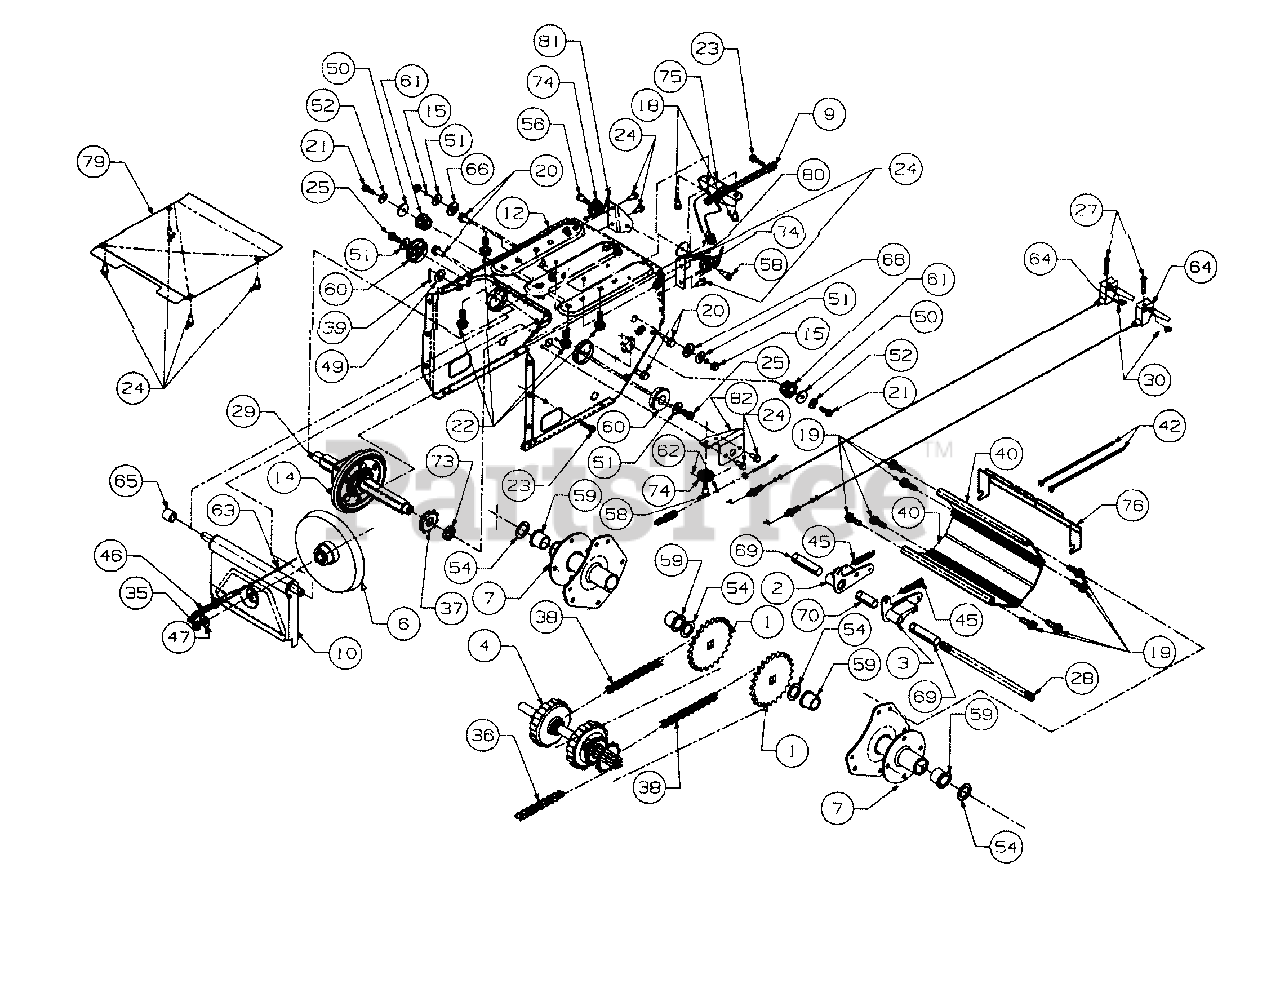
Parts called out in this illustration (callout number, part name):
1	Axle Assembly
2	Dog Assembly - R.H.
3	Dog Assembly - L.M.
4	Shaft Assembly
6	Disc Assembly
14	Wheel Assembly Friction
15	Screw
18	Screw
19	Screw
20	Screw
21	Screw
23	Screw
24	Screw
25	Screw
27	Screw
28	Shaft
29	Shaft
30	Nut Flange
35	Nut Jam
36	Chain
37	Sprocket
38	Chain
39	Pin Cotter
40	Housing Track
42	Cable Tie
45	Spring
46	Spring
47	Washer-Bell
49	Washer-Flat
50	Washer-Flat
51	Washer-Bell
52	Washer-Bell
54	Washer-Flat
56	Lubricant
58	Screw-Shoulder
59	Bearing-Flange
60	Bearing-Ball
61	Bearing-Hex Flange
62	Cable-Auger Clutch
63	Cable-Drive Clutch
64	Cable with Trigger Lever
65	Spacer
66	Spacer-Shoulder
69	Spacer-Split
70	Spacer-Split
73	Spacer
74	Roller-Cable
